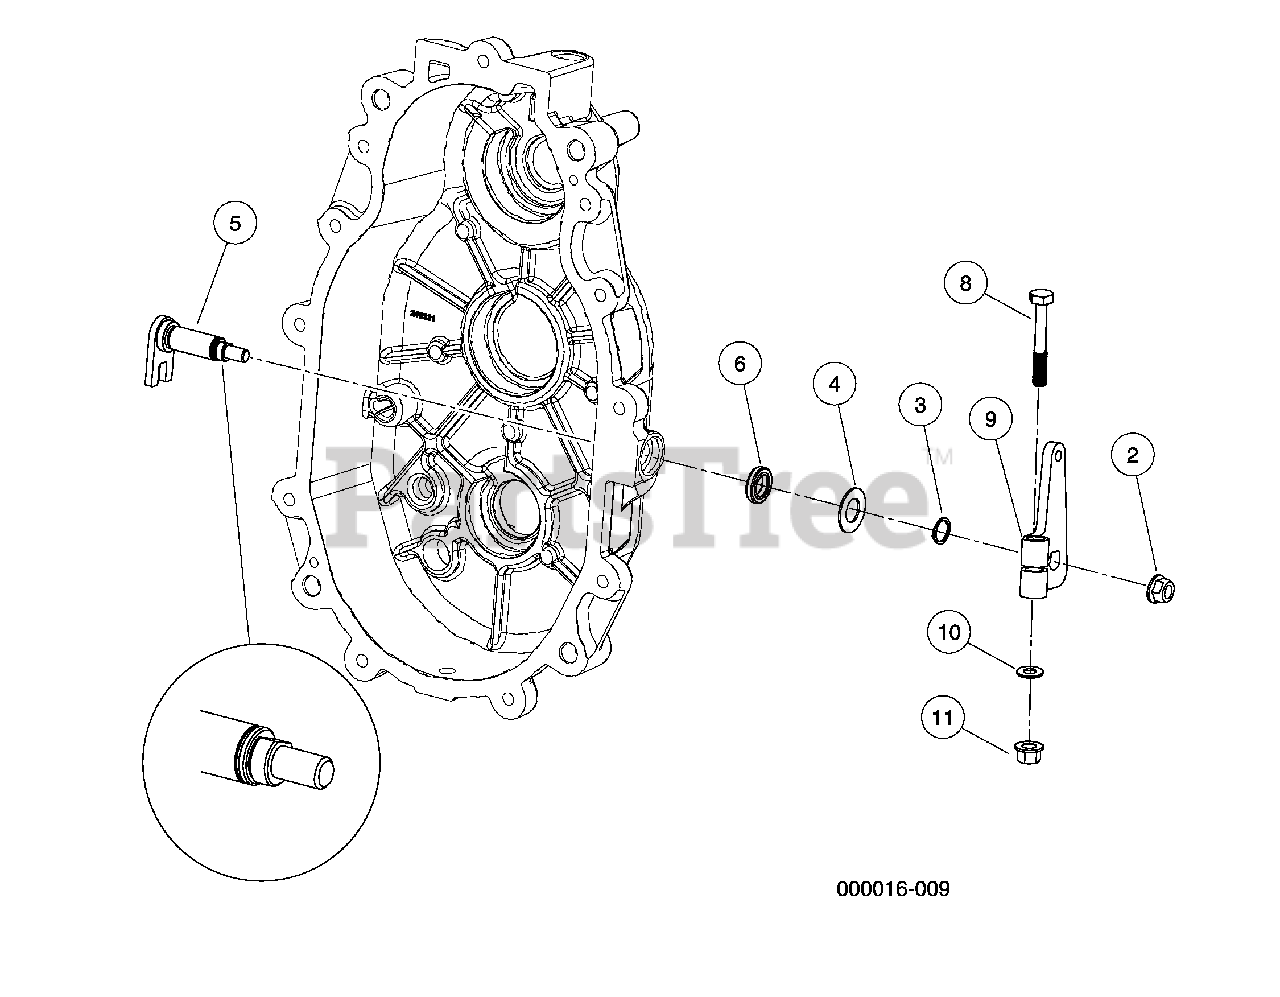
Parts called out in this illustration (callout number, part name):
1	Kit, Trans Shift Shaft Repair
2	Nut, Lock Hex, Nylon, 5/16-24
3	Ring, Retaining, External 9/16
4	Washer, Flat, .58 X 1.08 X .05
5	Weldment, Shift, Shaft
6	Seal, Dul Lip, .88 X .56 X .19
7	Kit, Bellcrank, D Shape, Clamp
8	Bolt, 3/8-16 X 2.00 Hex Head.
9	Asm, Bellcrank, D Shape, Clamp
10	Washer, 3/8 Type A Flat
11	Locknut, 3/8-16 Hex.
